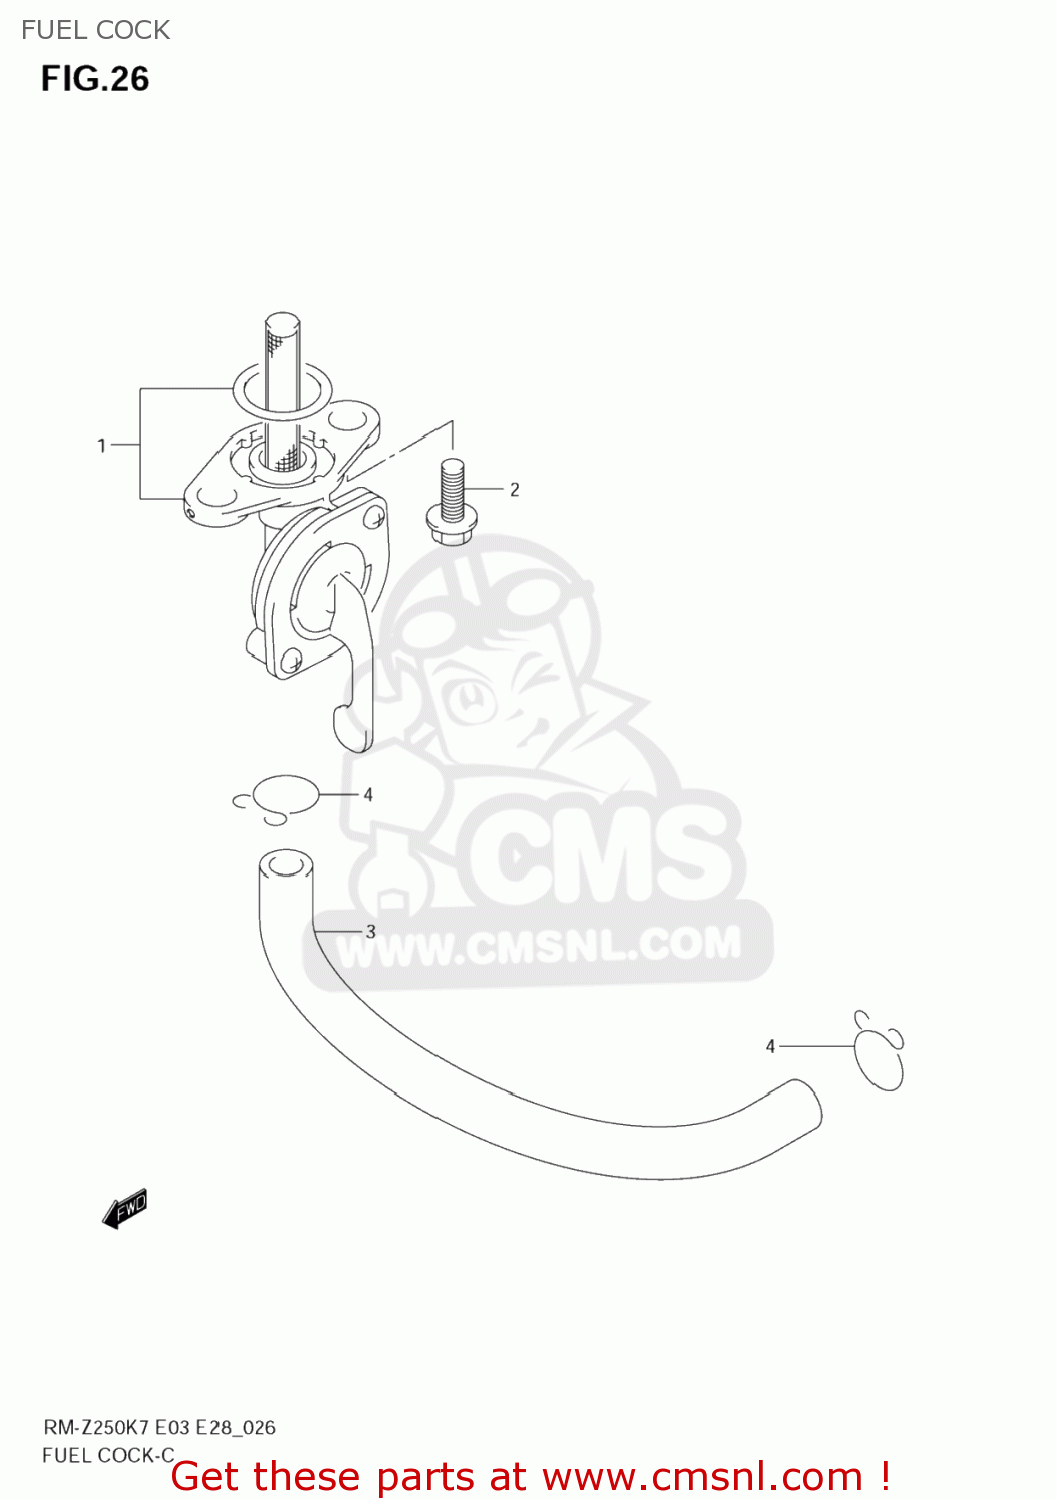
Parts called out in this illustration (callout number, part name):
1	COCK ASSY,FUEL
2	BOLT(6X12)
3	HOSE,FUEL
4	CLIP
